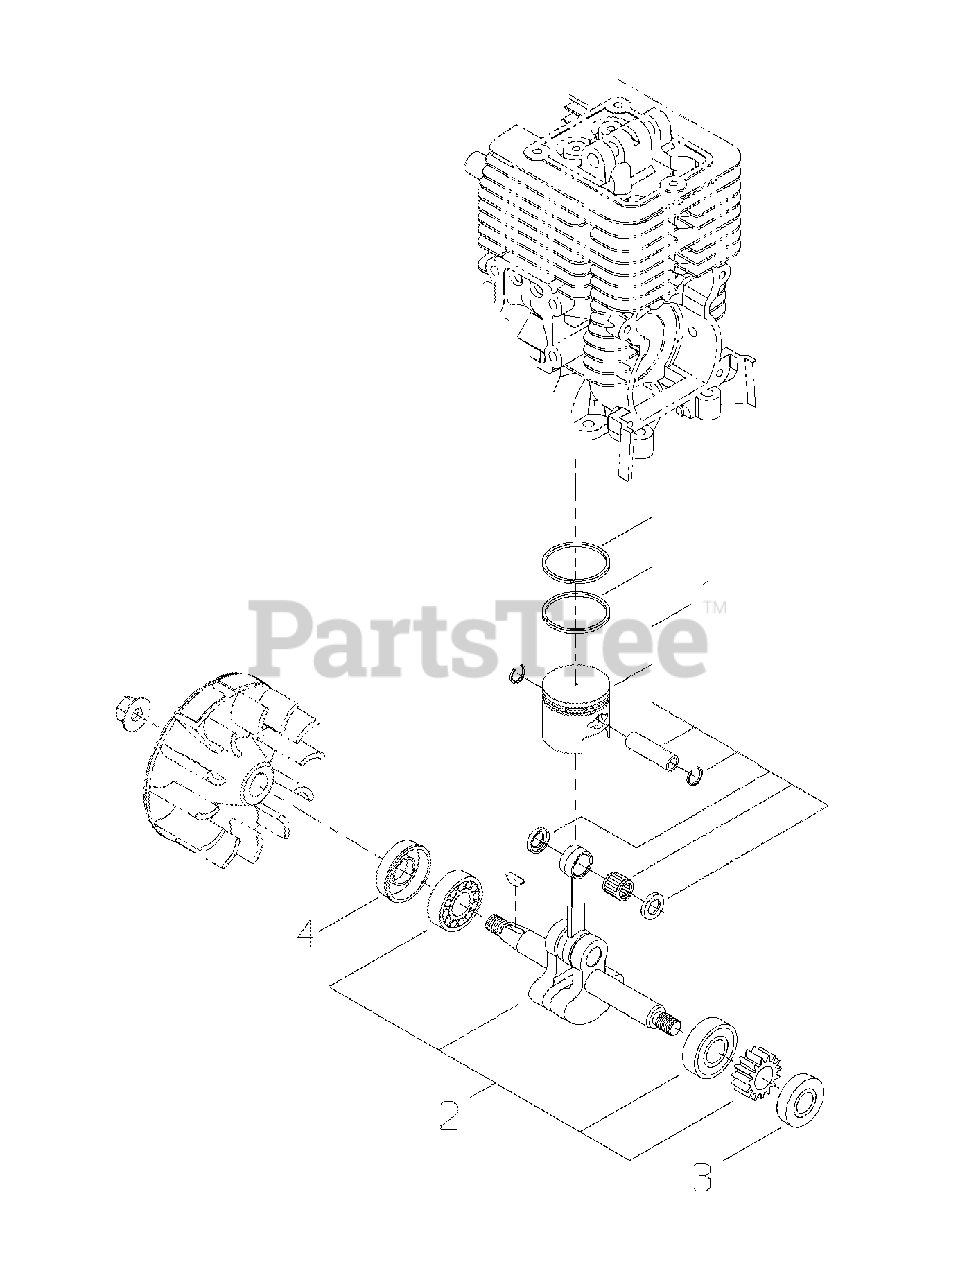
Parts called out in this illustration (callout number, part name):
1	PISTON KIT
2	CRANKSHAFT ASSY
3	SEAL, OIL 12
4	SEAL, OIL 12
